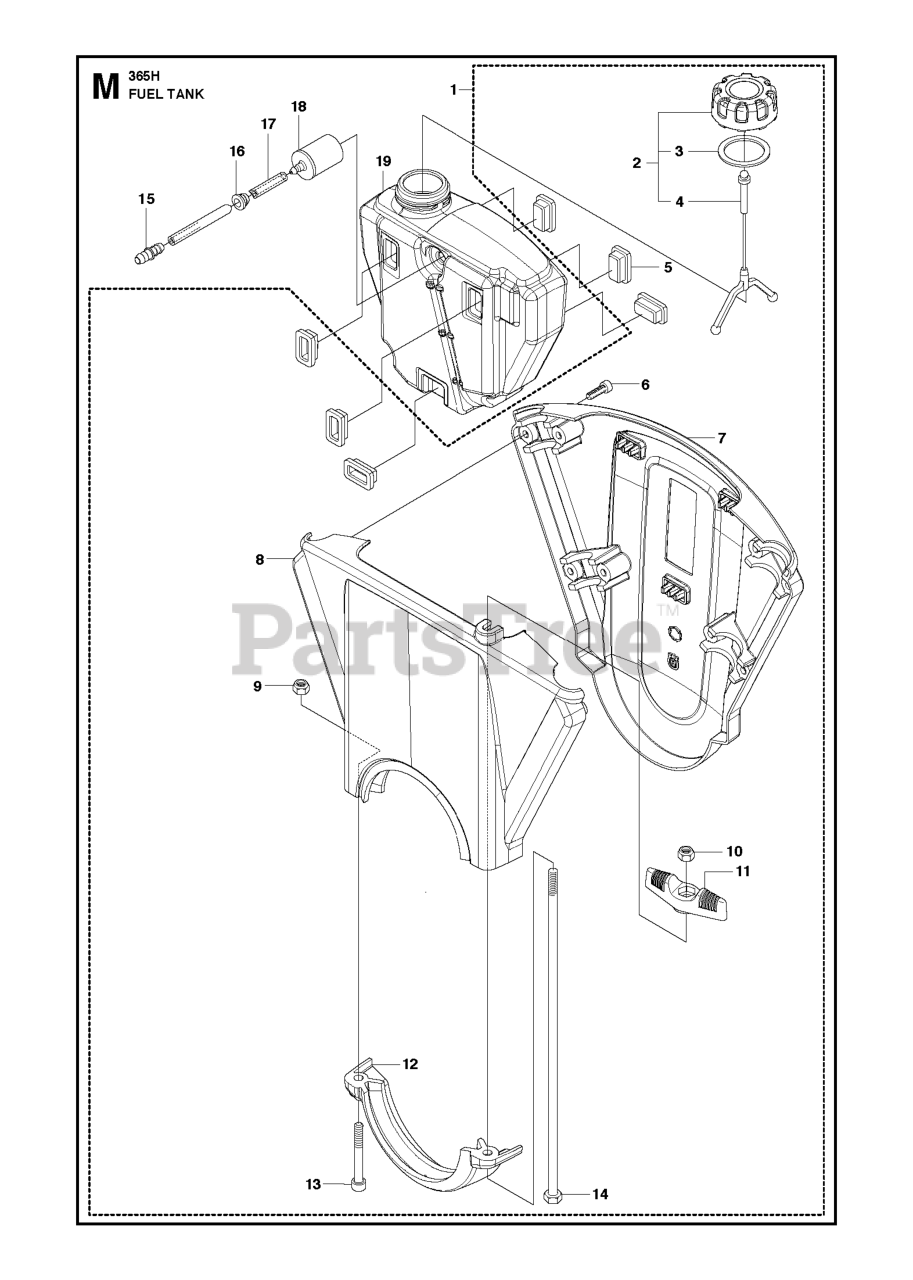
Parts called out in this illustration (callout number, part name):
1	TANK UNIT ASSY RESERVDEL
6	SCREW ITXSCM
7	TANK BRACKET BACK
8	TANK BRACKET FRONT
9	NUT FLANGE - M6
10	NUT FLANGE - M6
12	CLAMP TANK BRACKET
14	SCREW EHHM M6X225 8.8 ZPB
16	FUEL TANK BUSHING
17	FUEL HOSE STRAIGHT 355
18	RP FUEL FILTER
